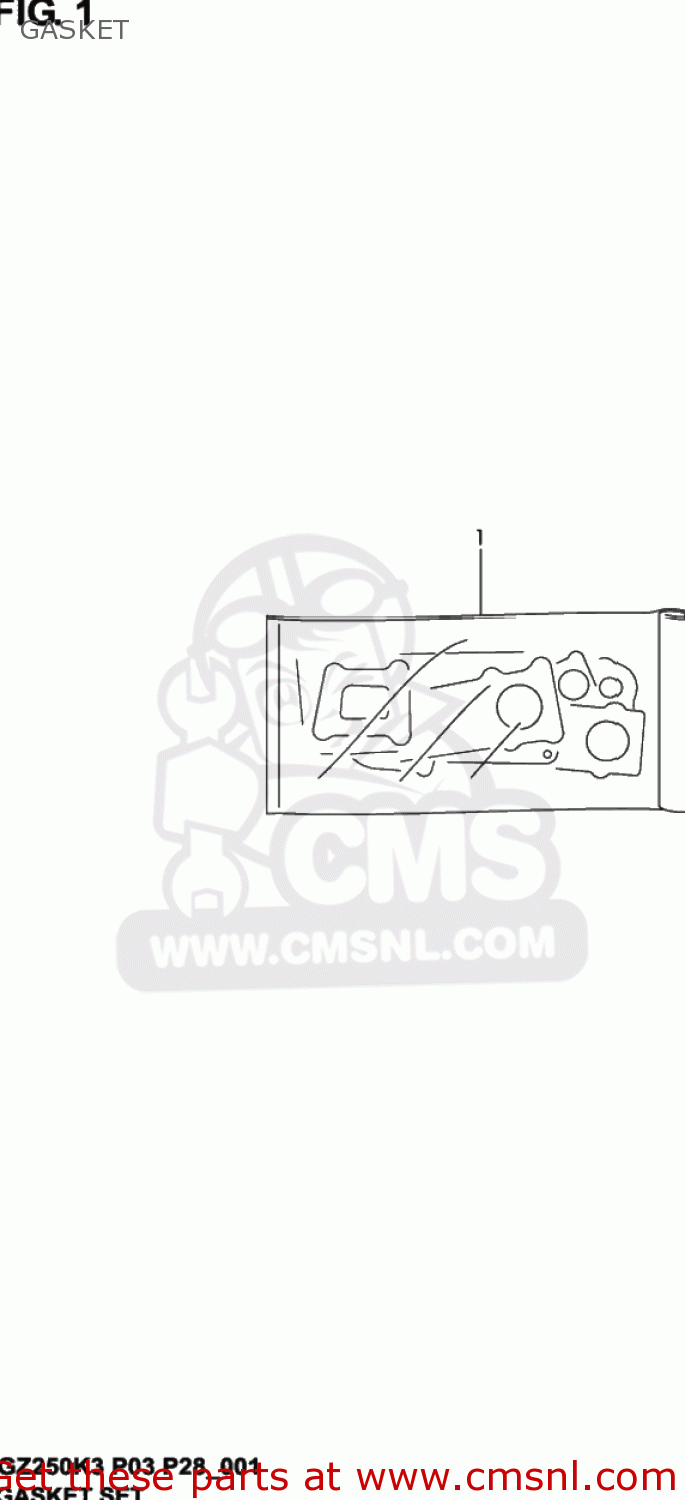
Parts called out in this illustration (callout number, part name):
1	GASKET SET (NAS)
2	GASKET,CYLINDER HEAD (NAS)
3	GASKET,CYLINDER (NAS)
4	GASKET,CLUTCH COVER (NAS)
5	GASKET,MAGNETO COVER (NAS)
6	GASKET,TENSIONER ADJUSTER (NAS)
7	GASKET,EXHAUST PIPE (NAS)
8	O RING(D:1.9,ID:8.6)
9	O RING(D:2.4,ID:15.8)
10	O RING(D:2.5,ID:21)
11	O RING(D:2.4,ID:26.2)
12	O RING(D:2.4,ID:39.7)
13	O RING(D:2.4,ID:23)
14	O RING(D:2.4,ID:73)
15	O RING(D:2.4,ID:85)
